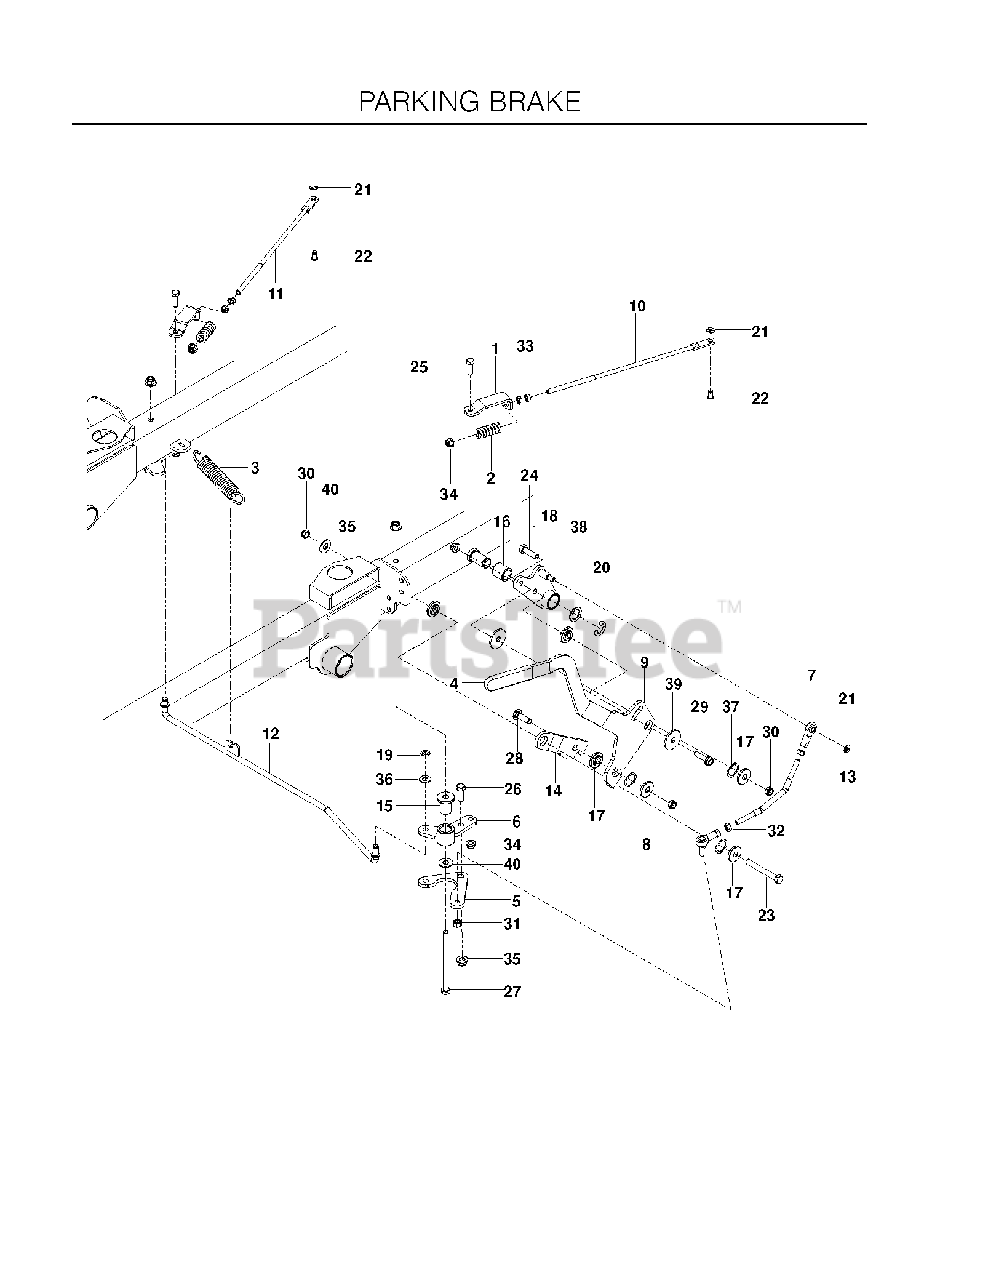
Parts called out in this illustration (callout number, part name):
1	BRACKET, BRAKE
5	PLATE, BRAKE, BLK
6	BELLCRANK, BRAKE, WLDMT
7	BALL JOINT, RIGHT HANDED
8	SPHERICAL ROD END, RH
9	LEVER, BRAKE, BLK
10	LINKAGE, BRAKE RR
11	LINKAGE, BRAKE, RT-RR
12	LINKAGE, BRAKE, PRIMARY
13	LINKAGE, BRAKE
14	LINK, FOLLOWER
15	BUSHING, PIVOT
16	BUSHING, SLEEVE 3/4 X 1.0
17	BUSHING, BRAKE
18	WELDMENT, ARM, BRAKE
19	E RING 3/8"
20	E RING 3/4
21	RING RETAINING EXT 5/16
22	PIN, BRAKE ARM
23	HCS 3/8C X 3
24	HCS 3/8C X 1 1/4
25	HCS 5/16C X 1
26	HCS 3/8C X 1
27	SCREW, 3/8C X 5 HEX CAP
28	RHSNB 3/8-16 X 1-1/4
29	HHFS 5/16-18 X 1.25 TPBLT GD 5
30	NUT HEX 3/8-16 NYLON, THIN
31	NUT 5/16F NYLOC
32	NUT 5/16F
33	NUT 5/16-18 HEX JAM ZD
34	5/16-18 NYLOC FLANGE NUT
35	NUT 3/8-16 HEX FLG NYLOC ZD
36	WASHER 3/8 SAE FLAT
37	WASHER, .825 X 1.087, WAVE
38	WASHER .787 X 1.125 X .06
39	WASHER, FRICTION, 1/8
40	WASHER 3/8 FLAT
